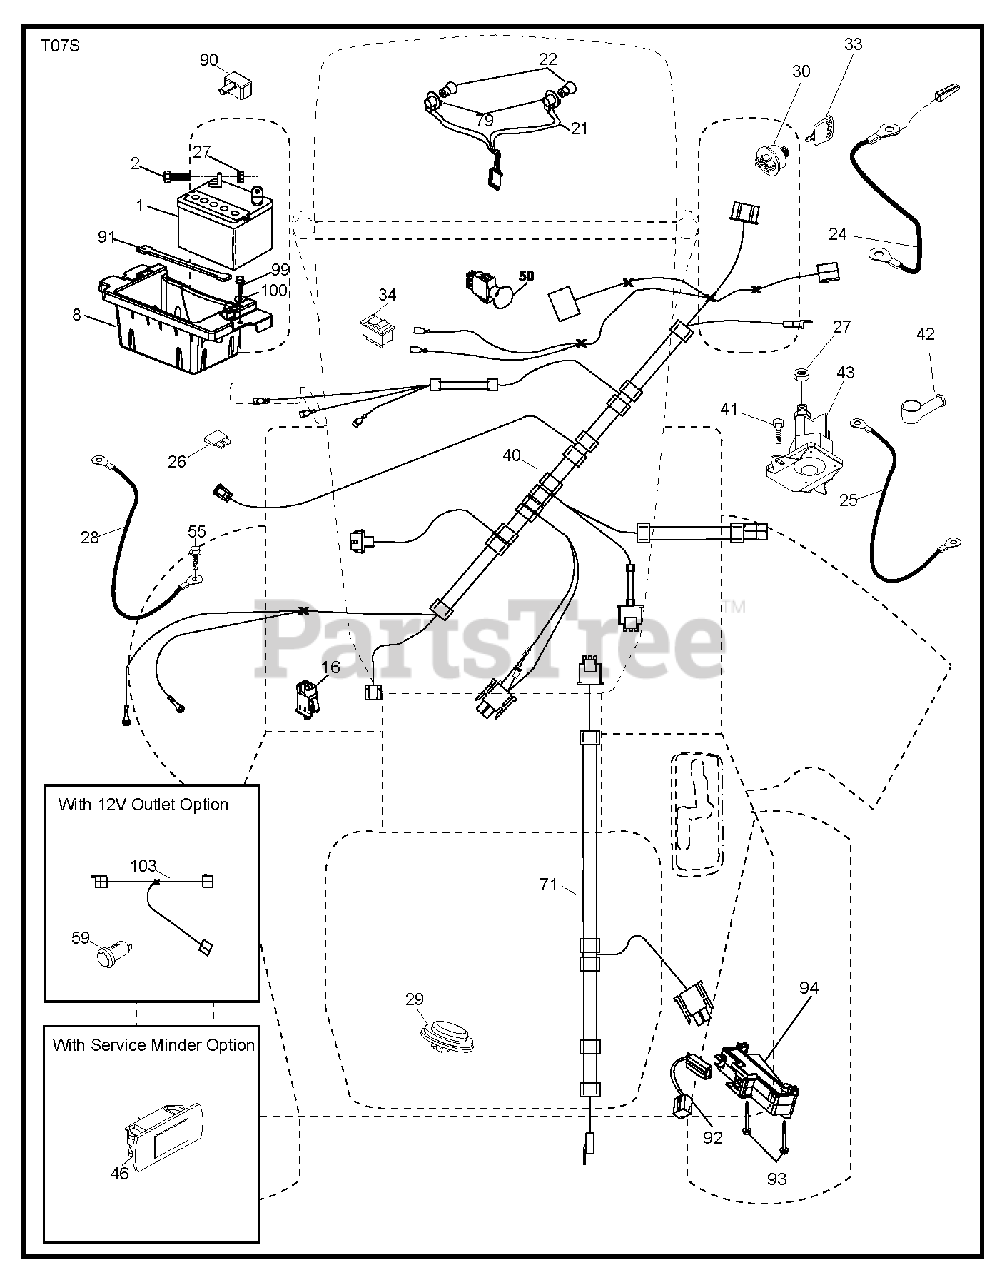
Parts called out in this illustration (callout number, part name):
1	BATTERY.DRY.30.AMP
2	BOLT.HEX.1/4.X.3/4.DICHROMATE
8	BOX.BATTERY.MOUNT.FRONT.LT
16	SWITCH INTERLOOK PUSH-IN
21	HARNESS.LIGHT W/4152J BULBS
24	CABLE.BATT.POS.WIRE.TG.DA SOL
25	CABLE.STARTER.6G.BL/RED.17.5
26	FUSE 20AMP
27	NUT
28	CABLE GROUND 6 GA 21" 90T BLK
29	SWITCH.SEAT.DELTA.OPC.
30	SWITCH.IGN.DELTA.W.LGH.ROS
33	KEY.CHAIN.BLISTER.PACK.GEN.USA
40	HARNESS.IGN.DASH.HUQ/P
41	SCREW
42	TERMINAL COVER
43	SOLENOID.W/BRASS.PLUNGER
46	RP GUAGE.SRVCMNDR.HRMTR.
50	RP SWTICH.PTO.8.TERMINAL
55	SCREW 5/16"
59	OUTLET.12-VOLT
71	HARNESS-CHASSIS SUB
79	BULB HOLDER ASM.
90	COVER.TERMINAL.BATTERY
91	STRAP.BATTERY.MOUNT.FRONT(2 2)
92	HARNESS.PIGTAIL.CONSLE
93	SCREW.PLASTITE
94	MODULE.REVERSE.ROS
99	SCREW HEXWSHR 1/4-20X3/4
103	HARNESS PIGTAIL 12V OUTLET
